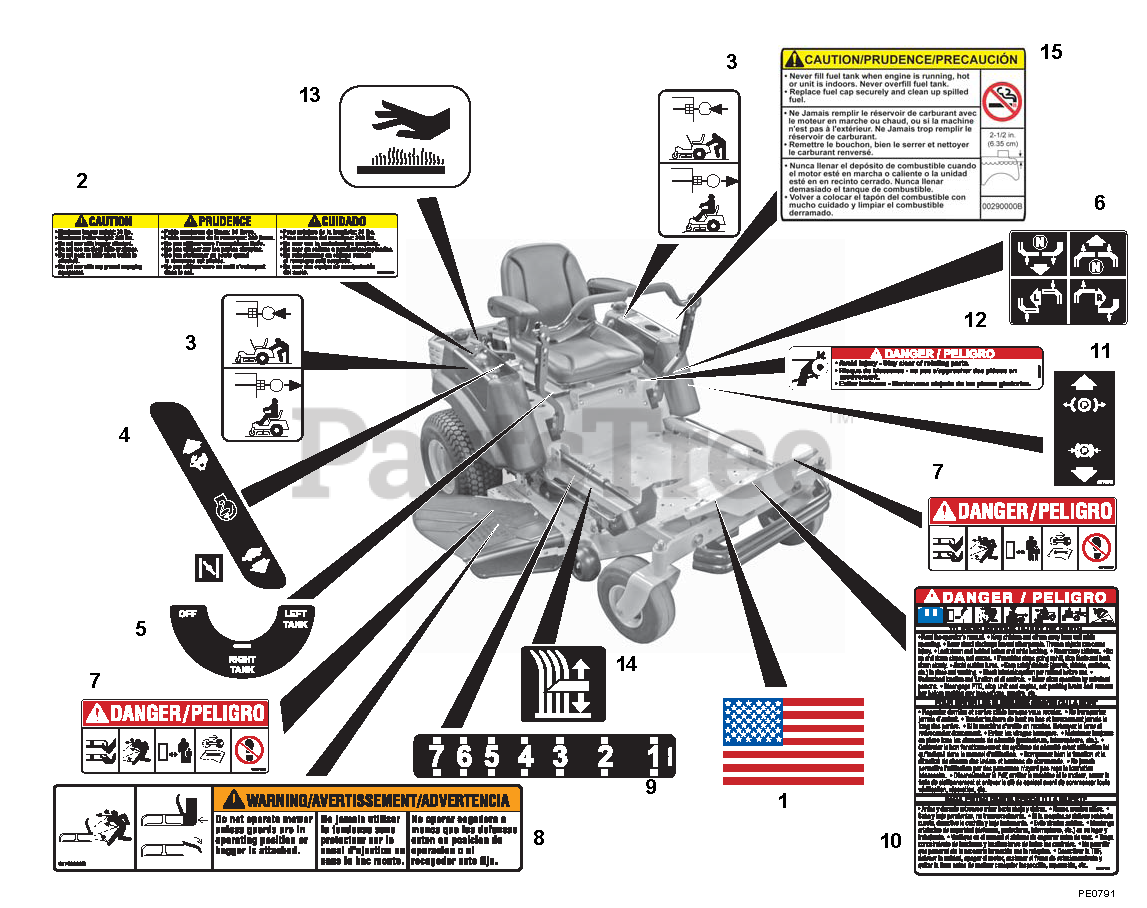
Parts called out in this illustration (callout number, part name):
1	DECAL, AMERICAN FLAG
2	DECAL, TRAILER HITCH
3	DECAL, TRANSMISSION DISCONNECT
4	DECAL, SPEED CONTROL
5	DECAL, FUEL VALVE
6	DECAL, INSTRUCTIONAL-STEERING
7	DECAL, MOWER PAN DANGER
8	DECAL, WARNING
9	DECAL CUT HEIGHT
10	DECAL, DANGER BILINGUAL
11	DECAL, PARKING BRAKE LEVER
12	DECAL- DANGER
13	DECAL, HOT SURFACE
14	DECAL-CUT HEIGHT
15	DECAL,FUEL WARNING
